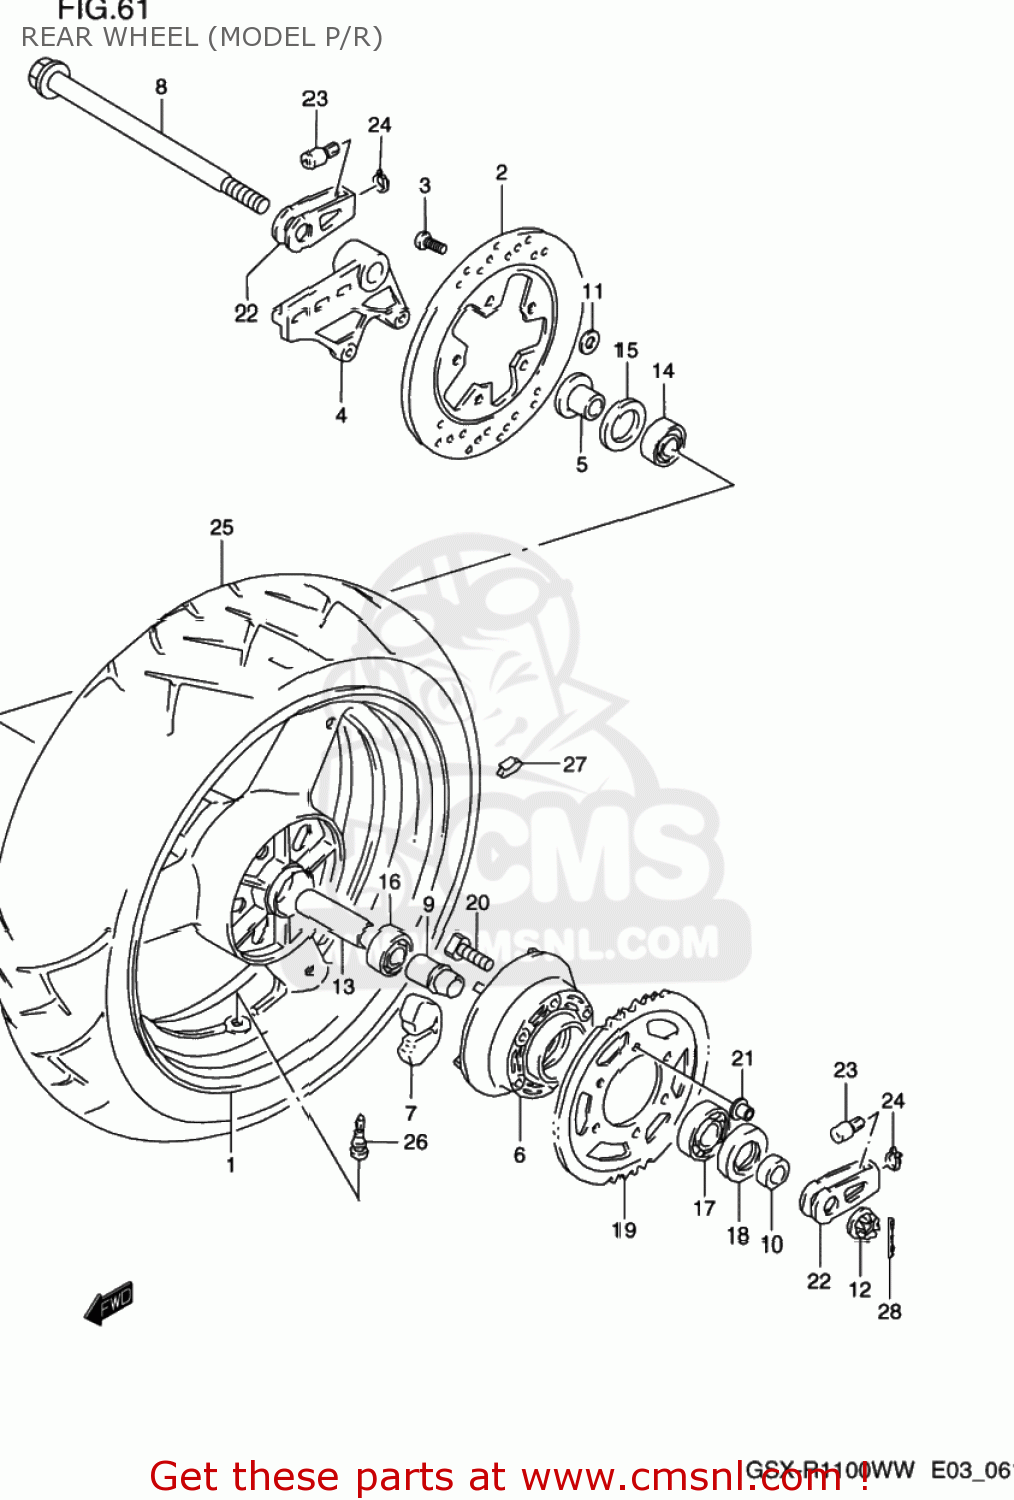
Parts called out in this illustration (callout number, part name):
1	WHEEL,RR(17XMT5.50)
2	DISC,RR BRAKE
3	BOLT 8X33
4	BRACKET,REAR CALIPER
5	SPACER,RR AXLE,R
6	DRUM,RR SPROCKET
7	ABSORBER,RR HUB SHOCK
8	AXLE,RR
9	RETAINER,RR HUB BEARING
10	SPACER,RR AXLE,L
11	SHIM(10X20X0.3) (NAS)
12	NUT
13	SPACER,RR WHEEL HUB BEARING
14	BEARING(20X47X14)
15	SEAL,OIL(28X47X7)
16	BEARING(20X47X14)
17	BEARING(25X62X17)
18	SEAL,OIL(35X62X8)
19	SPROCKET,RR(532-42T)
20	BOLT
21	NUT
22	ADJUSTER,CHAIN
23	ADJUSTER,CHAIN
24	CIRCLIP
25	TIRE COMP,REAR 180/55ZR1
26	VALVE ASSEMBLY,WHEEL,TR412
27	BALANCER,WHEEL
28	PIN, COTTER
